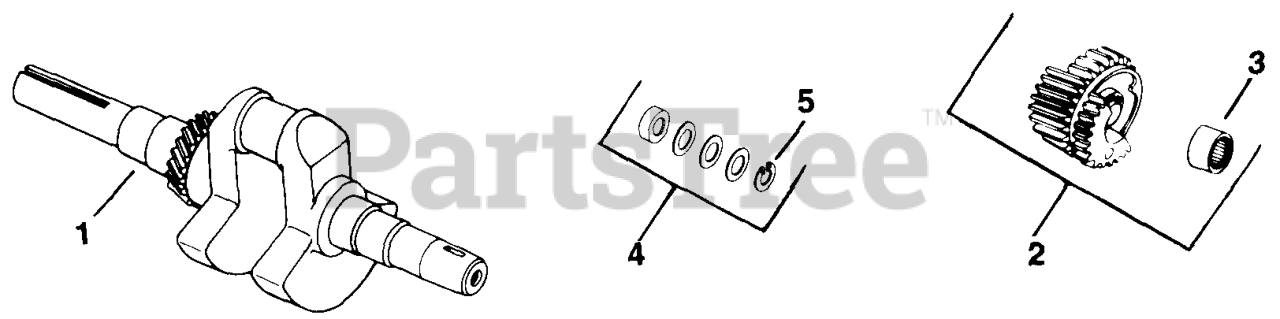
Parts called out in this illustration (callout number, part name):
1	CRANKSHAFT KIT - DISCONTINUED
2	GEAR
3	BEARING
4	KIT, SPACER
